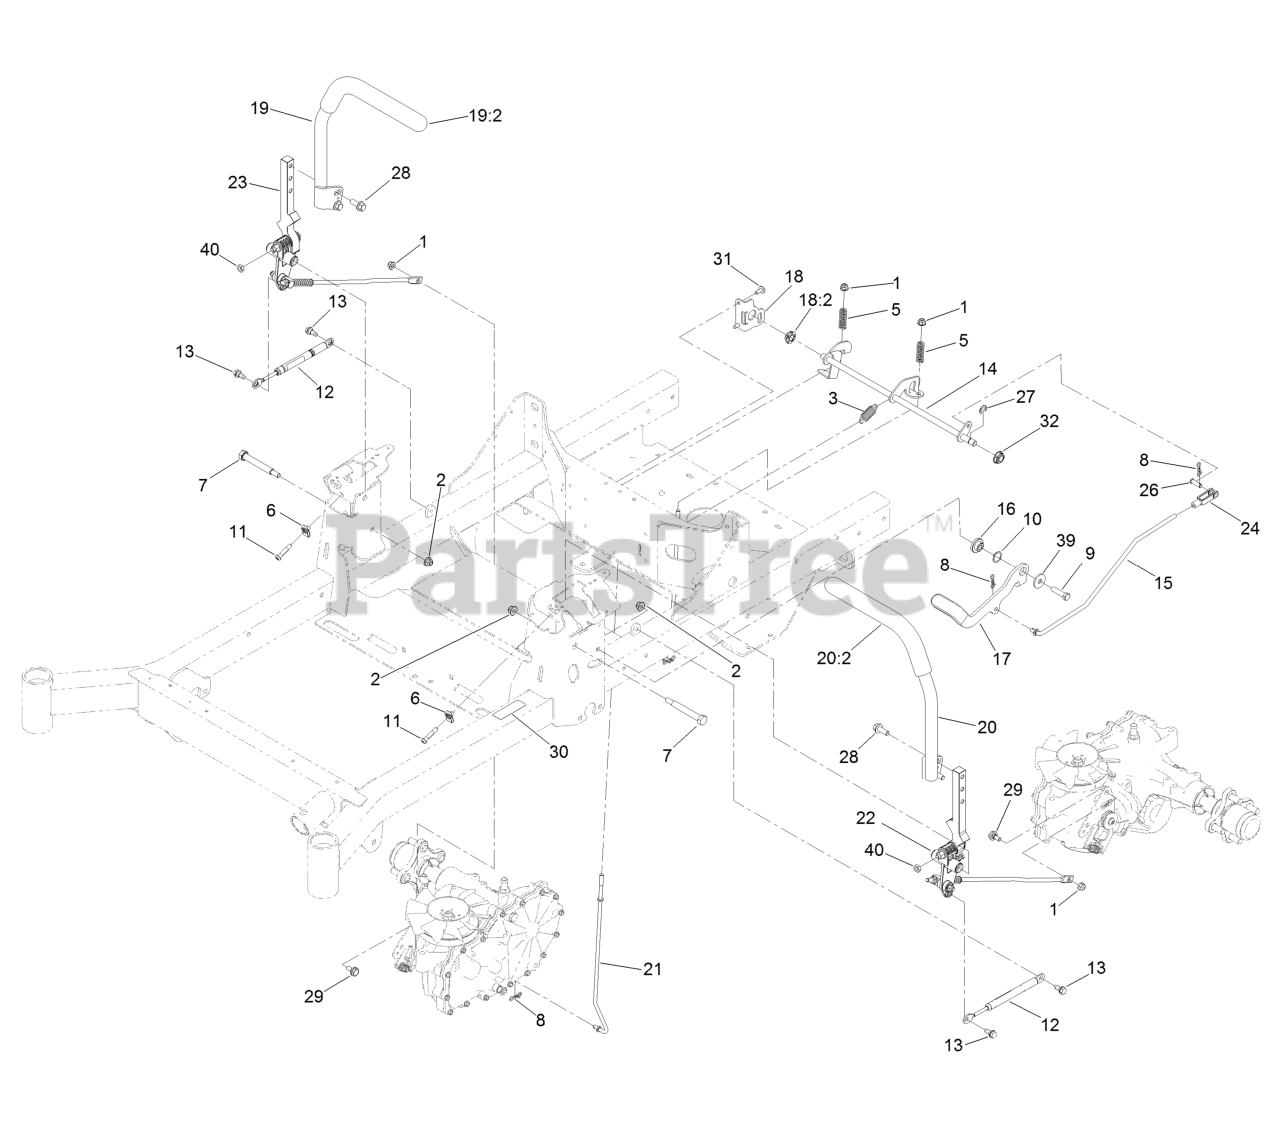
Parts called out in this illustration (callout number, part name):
1	Nut-HF, NI
2	Nut-HF, NI
3	Spring-Extension
5	Spring-Compression
7	Bolt-Pivot
8	Pin-Cotter, Locking
9	Screw-HH
10	Washer-Wave
11	Screw-HSBH
13	Screw-Shoulder
14	Shaft-Brake
15	Linkage-Brake, Upper
16	Pivot-Flange
17	Lever-Brake (With Grip)
18	Bracket-Brake
18:2	Bearing-Spherical
19	RH Control Handle ASM
20	LH Control Handle ASM
21	Linkage-Brake, Lower
22	LH Motion Control ASM
23	RH Motion Control ASM
24	Yoke-Adjustable
26	Pin-Clevis
27	Ring-Retaining, External
28	Screw-HHF
29	Bolt-Shoulder
30	Decal-Brake, Parking
31	Screw-Torx
32	Bearing-Spherical
39	Washer
40	Nut-Jam
